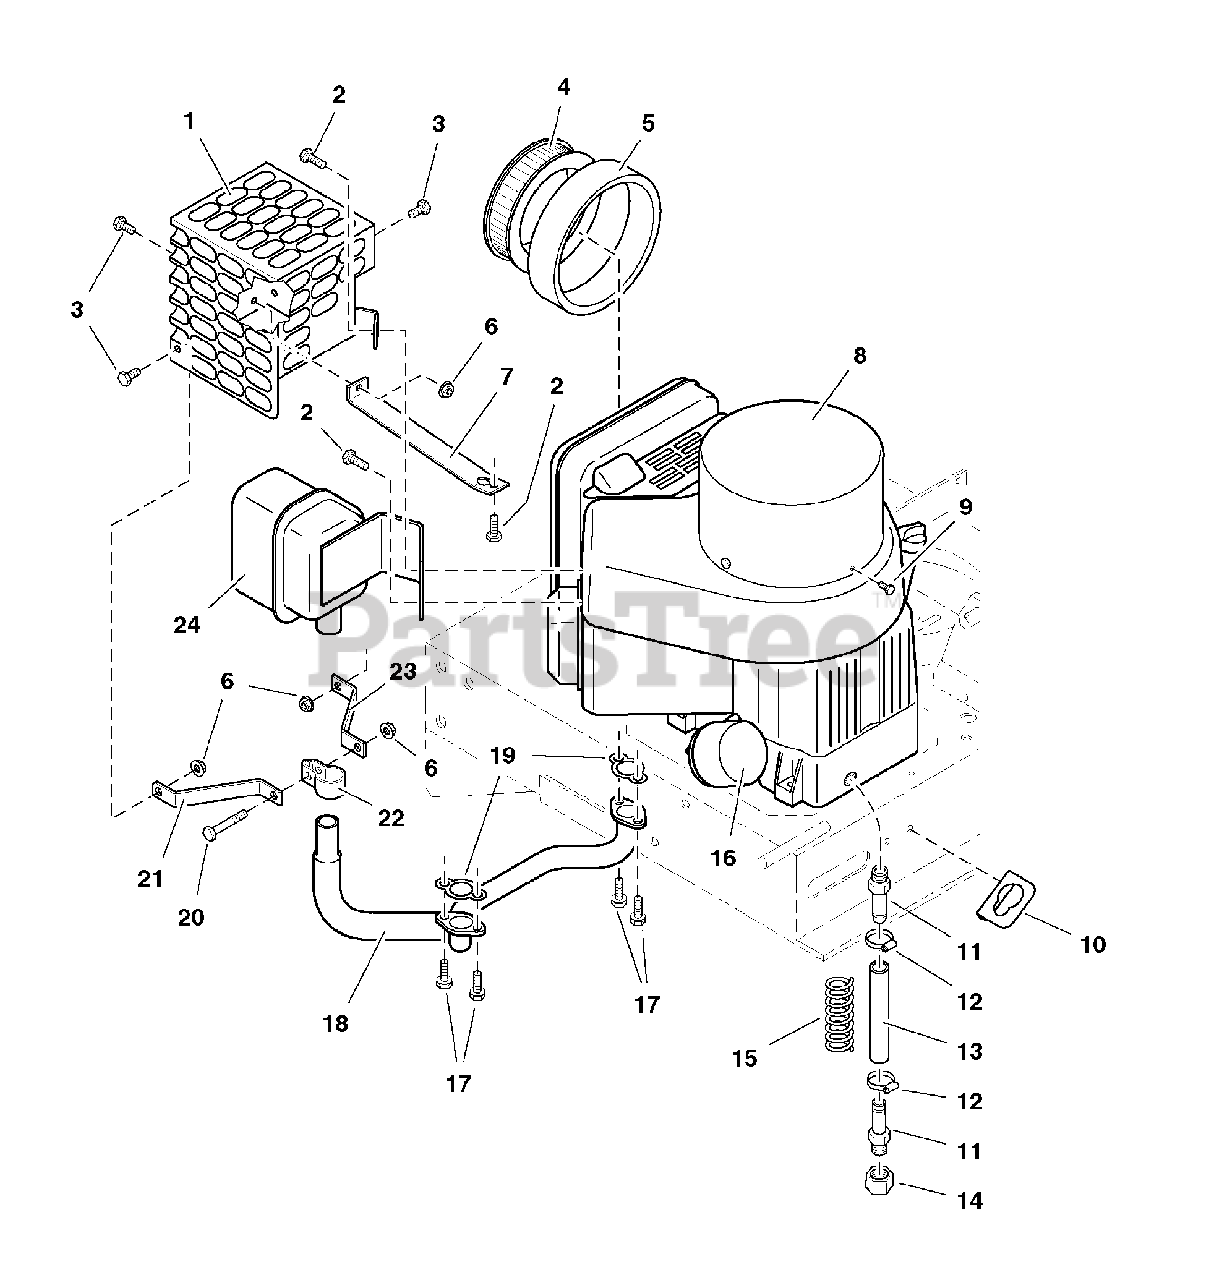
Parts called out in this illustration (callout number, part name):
1	MUFFLER GUARD
3	CAPSCREW, Hex Hd, 5/16-18 x 3/4
6	NUT, Hex, Serrated Flange, 5/16-18
7	BRACKET, Bottom
10	OIL DRAIN ANCHOR
11	FITTING, 3/8NPT - 1/2 Str.
14	CAP, 3/8NPT
15	SPRING, Compression
16	OIL FILTER (492932)
20	CAPSCREW, Hex Hd, 5/16-18 x 2
21	BRACKET, Front, Left
23	BRACKET, Front-Right
